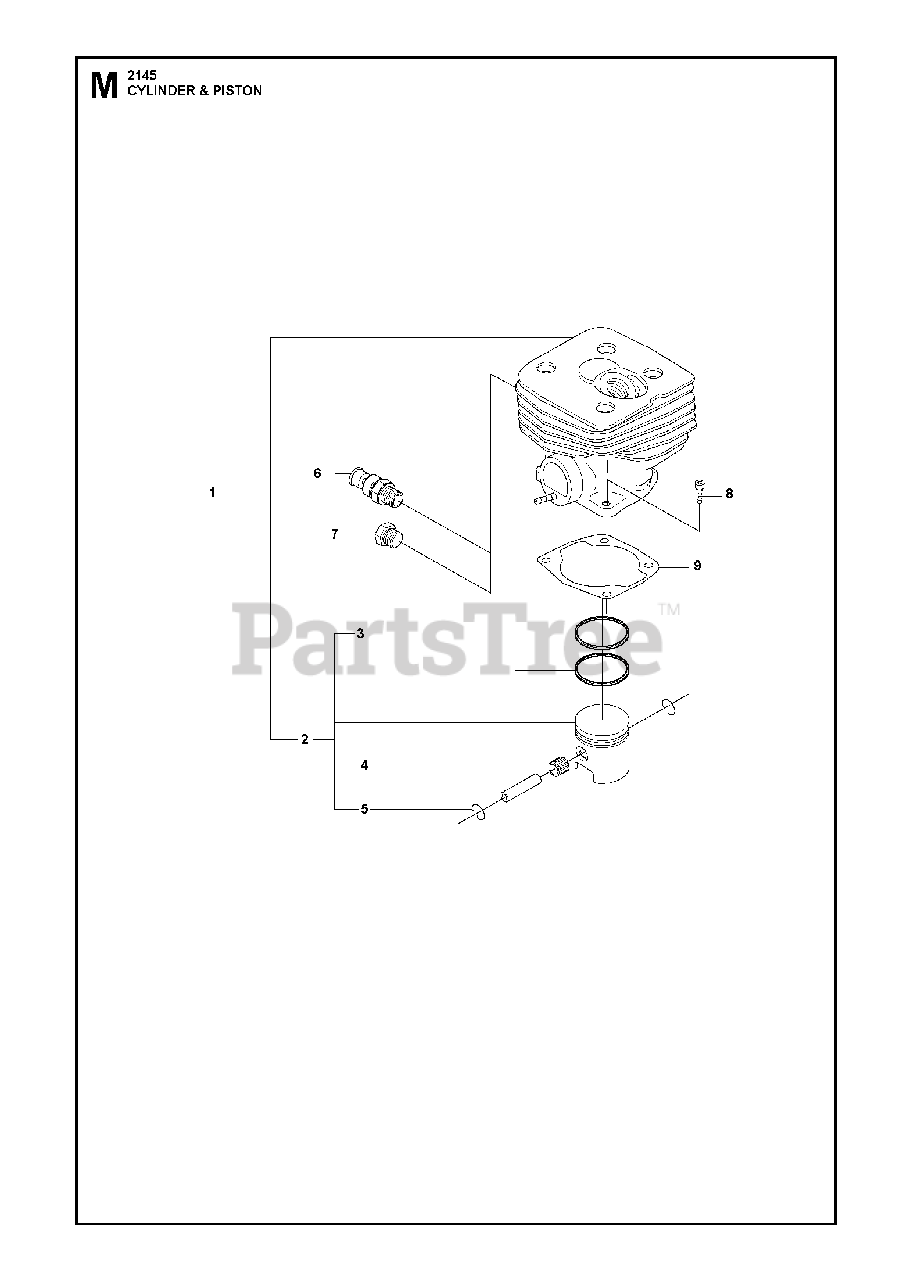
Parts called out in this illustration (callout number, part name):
1	CYLINDER ASSY
2	PISTON ASSEMBLY
2	RP PISTON ASSY
3	PISTON RING
4	RP SUPPORT BUSHING
5	LOCKING RING
6	DECOMPRESSION VALVE
7	CYLINDER PLUG
8	SCREW MC6S 5X20
9	GASKET
